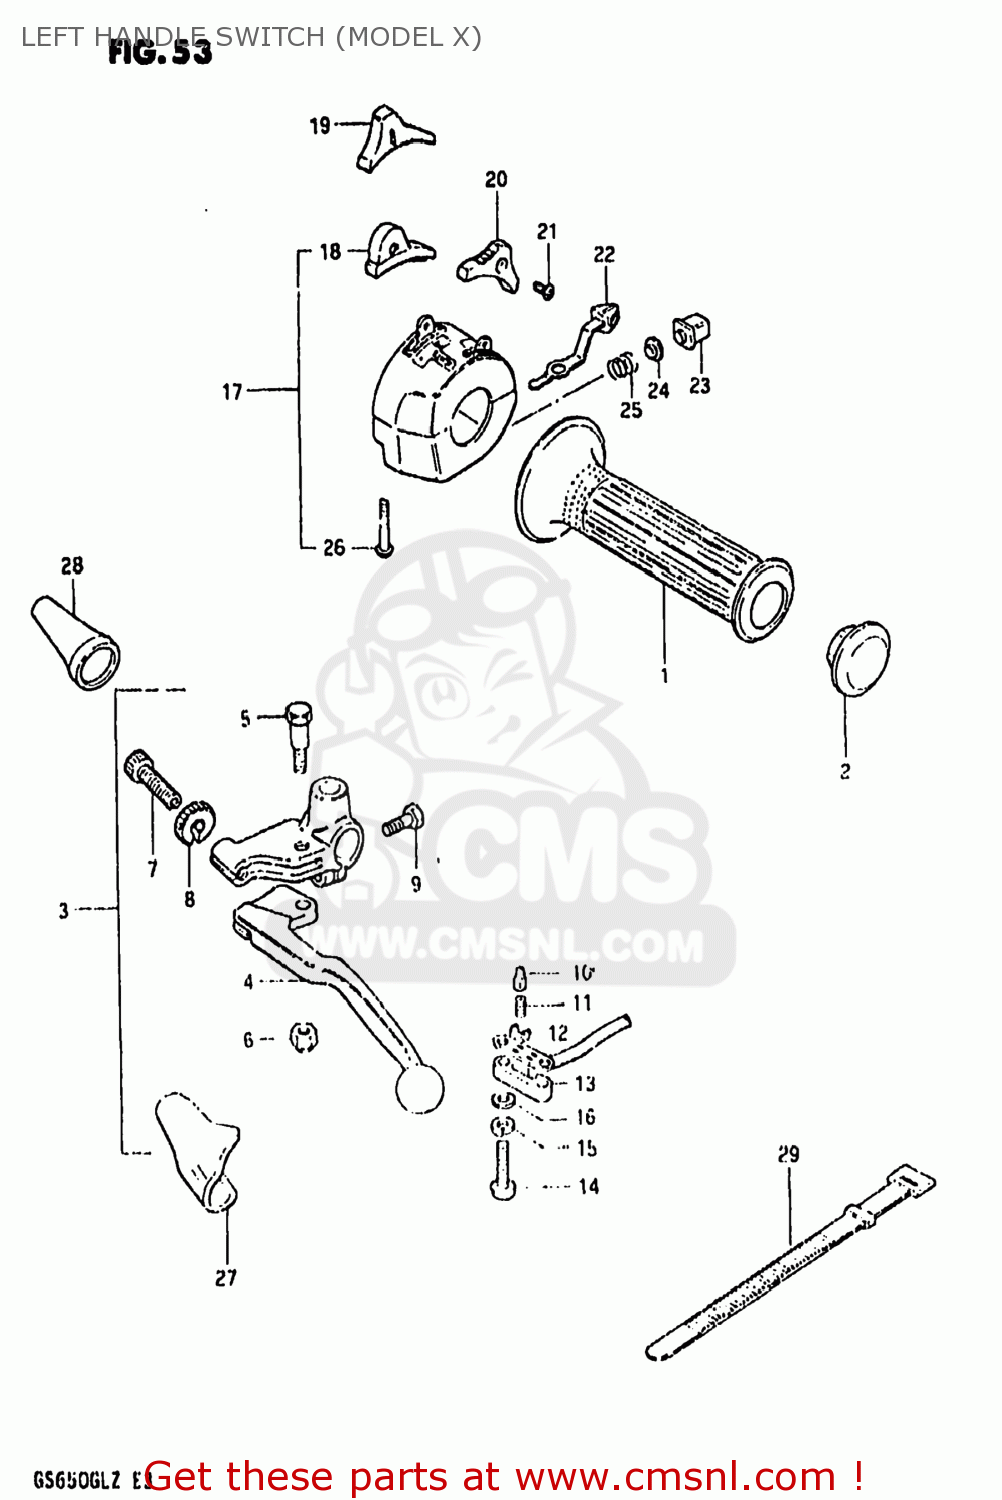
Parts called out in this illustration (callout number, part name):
1	GRIP,LEFT
2	CAP,GRIP END
3	LEVER ASSEMBLY
4	LEVER,CLUTCH
5	BOLT,LEVER
6	NUT 6MM
7	ADJUSTER,CABLE
8	NUT,CABLE ADJUSTER
9	BOLT,CLUTCH LEVER HOLDER
10	HOLDER
11	SPRING
12	PLATE
13	COVER,FR BK TERMINAL BASE
14	SCREW
15	LOCK WASHER
16	WASHER
17	SWITCH ASSY,HANDLE,L
18	KNOB,STOP
19	KNOB,LIGHTING SWITCH
20	KNOB,DIMMER SWITCH
21	SCREW
22	KNOB,TURNSIGNAL
23	BUTTON,HORN
24	CONTACT
25	SPRING
26	SCREW
27	COVER,CLUTCH LEVER
28	BOOT,CLUTCH CABLE
29	CLAMP(L:120)
